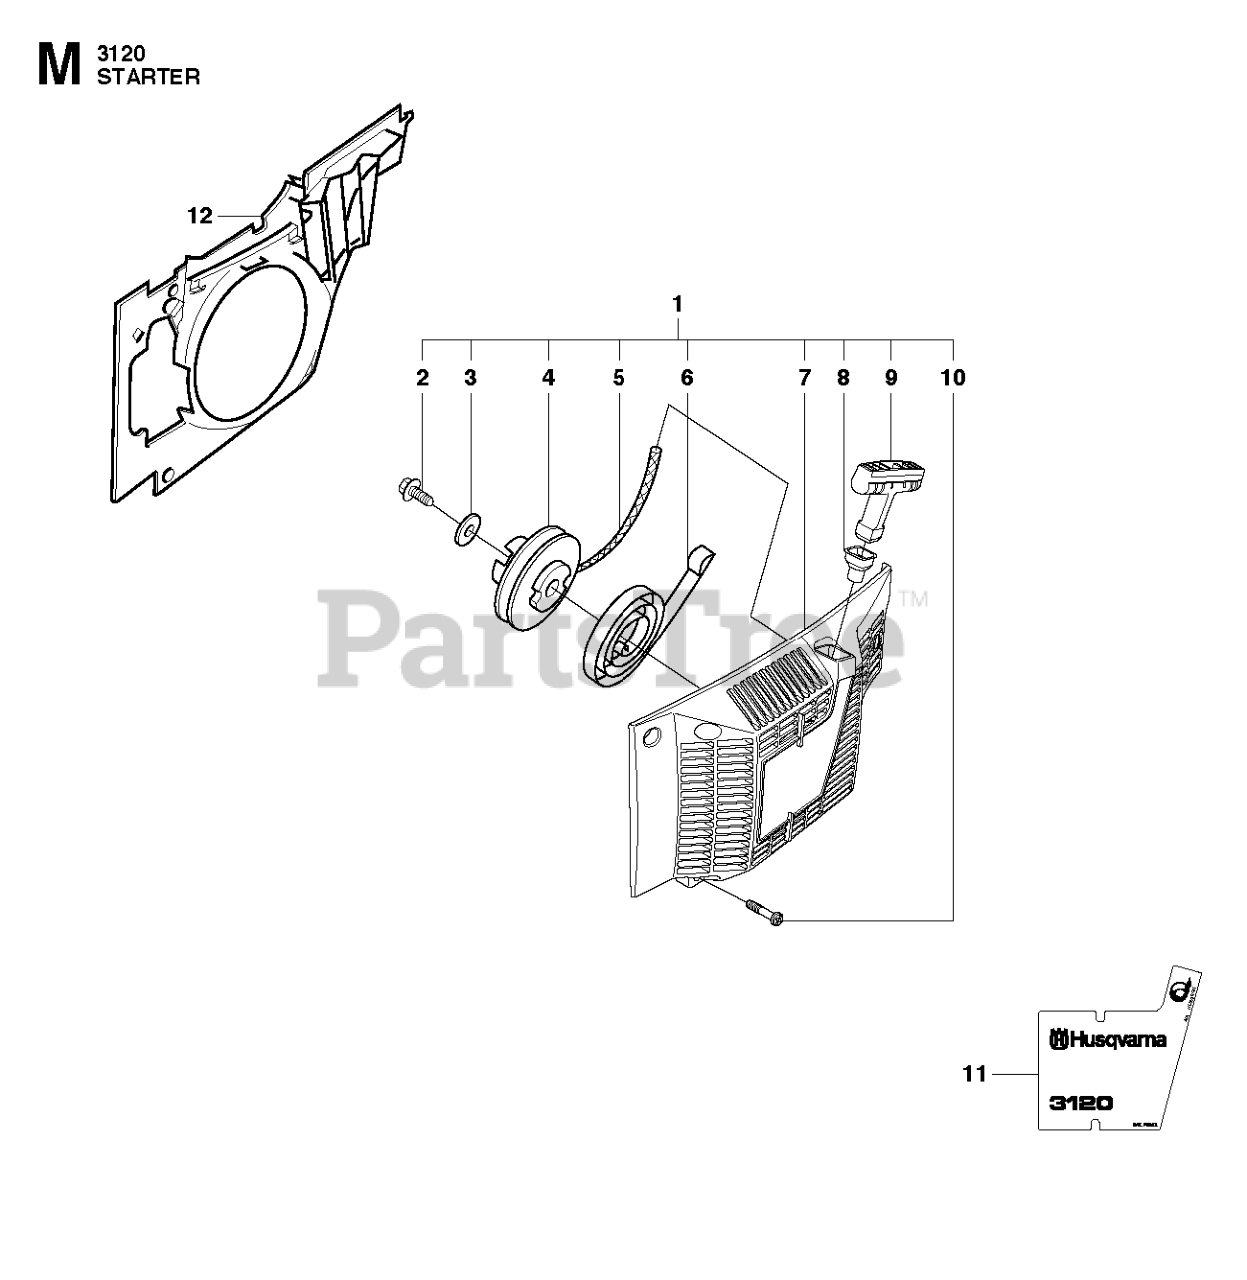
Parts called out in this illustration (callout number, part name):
1	STARTER ASSY
2	SCREW IHSCFT PW5.5X16 8.8 ZN/
5	STARTER ROPE
6	RECOIL SPRING
7	STARTER HOUSING
9	STARTER HANDLE
10	SCREW
12	AIR CONDUCTOR
